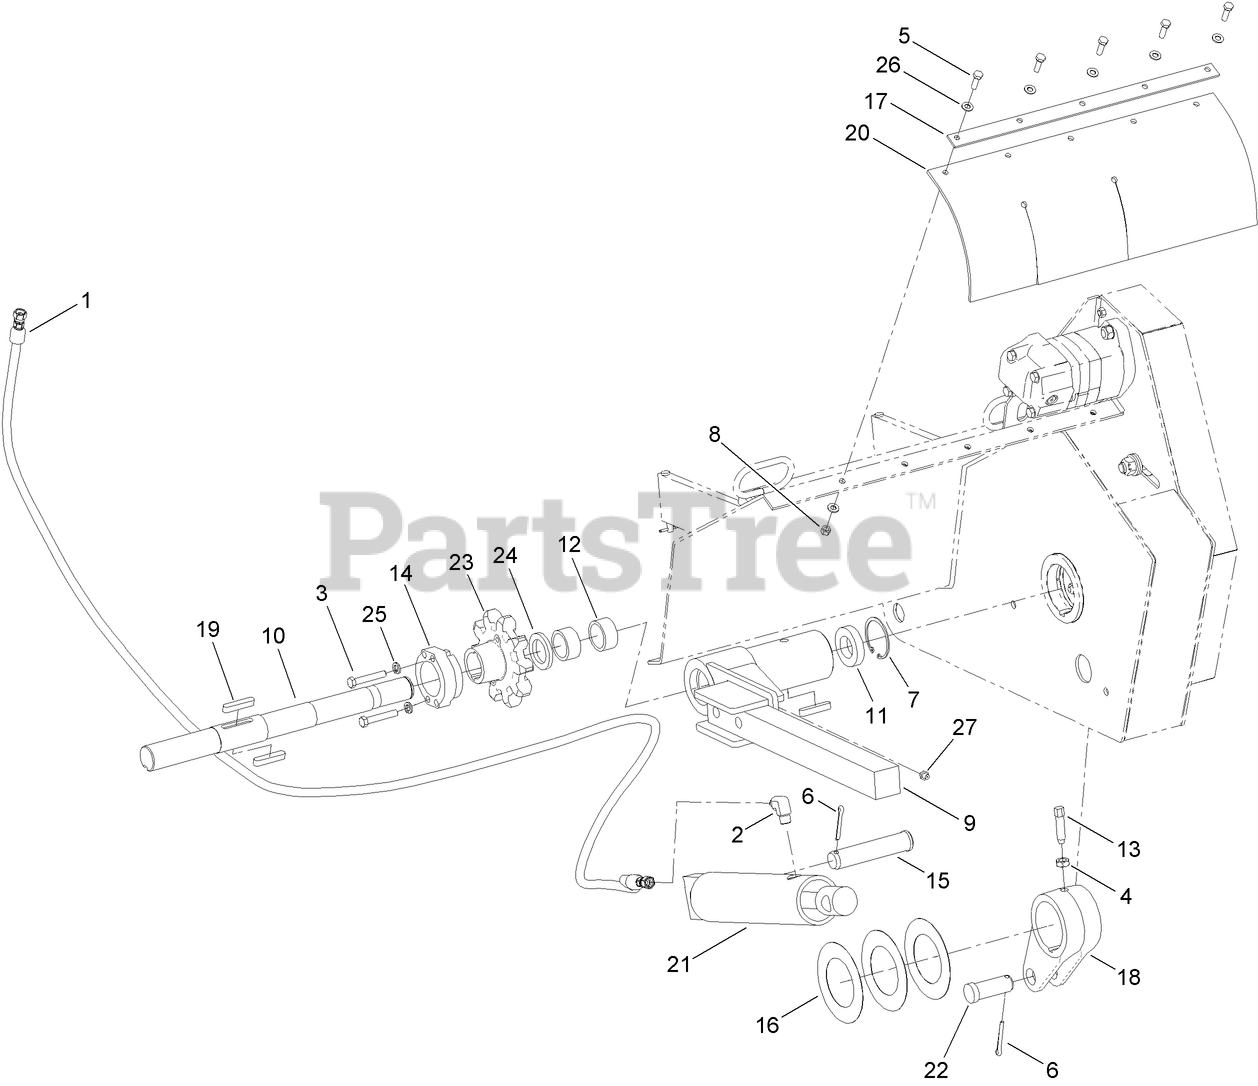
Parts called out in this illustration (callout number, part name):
1	HYD HOSE ASM
2	FITTING-ELBOW, 90 DEG
3	SCREW-HH
5	SCREW-HH
6	PIN-COTTER
7	RING-SNAP, INTERNAL
8	NUT-LOCK, CONE
9	MOUNT-BOOM
10	SHAFT-DRIVE, TRENCHER
11	BEARING
12	BEARING-NEEDLE
13	SCREW-SET, DOG POINT
17	STRIP-BACK
18	CRANK (BOOM CYLINDER)
20	FLAP-DIRT
21	HYD CYLINDER ASM
22	PIN-CLEVIS
23	SPROCKET
24	SEAL-OIL
25	WASHER-LOCK
26	WASHER-PLAIN
27	FITTING-GREASE
